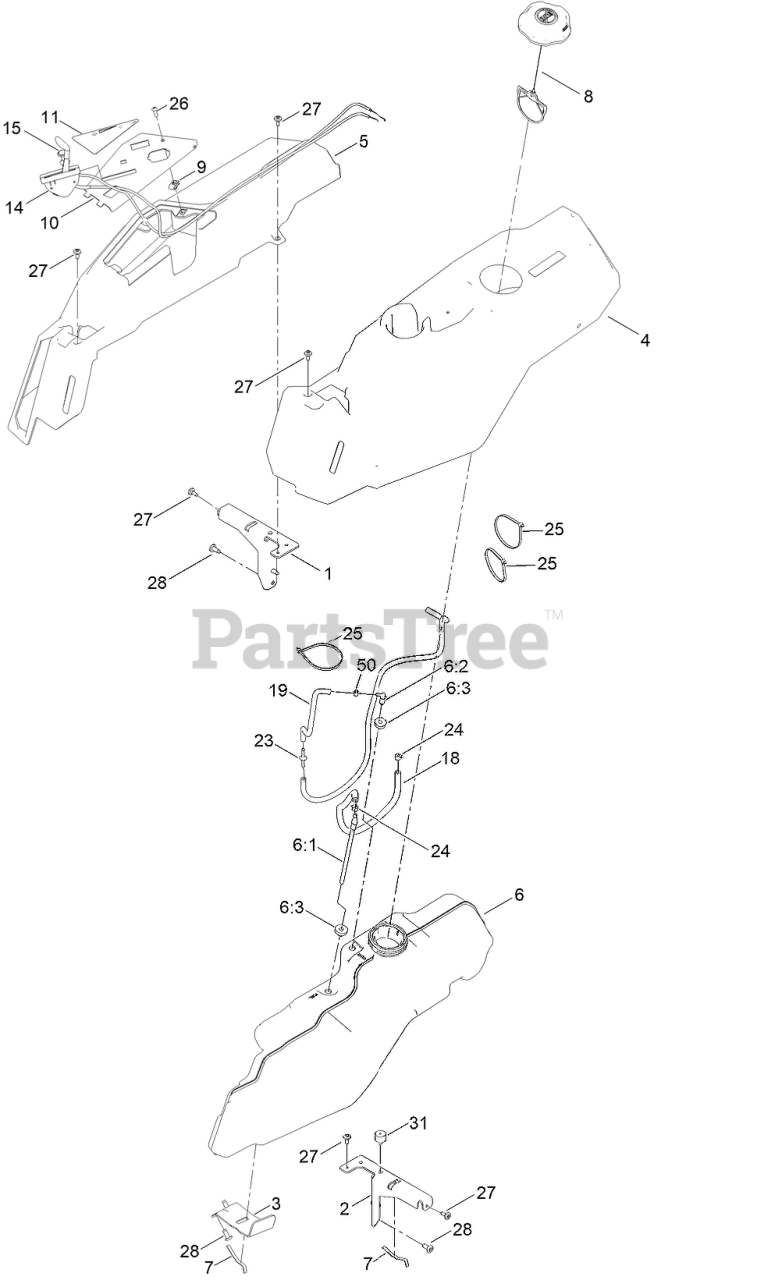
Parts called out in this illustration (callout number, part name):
1	SUPPORT-POD, RH
2	SUPPORT-POD, LH
3	SUPPORT-TANK, FUEL
4	POD-LH
5	POD-RH
6	TANK-FUEL ASM
6:1	CONNECTOR-ELBOW, 90 DEG
6:2	FITTING-ELBOW 90
6:3	BUSHING
7	SPRING
8	CAP-FUEL, RATCHETING
10	PANEL - CONTROL
11	DECAL-PANEL, CONTROL
14	CABLE-THROTTLE
15	CABLE-CHOKE
18	HOSE-FUEL
19	HOSE-FUEL
23	ADAPTER ORIFICE
24	CLAMP-HOSE
25	TIE-CABLE
26	SCREW-PRH
27	SCREW-SHOULDER
31	BUMPER-GROMMET
50	CLAMP-HOSE
